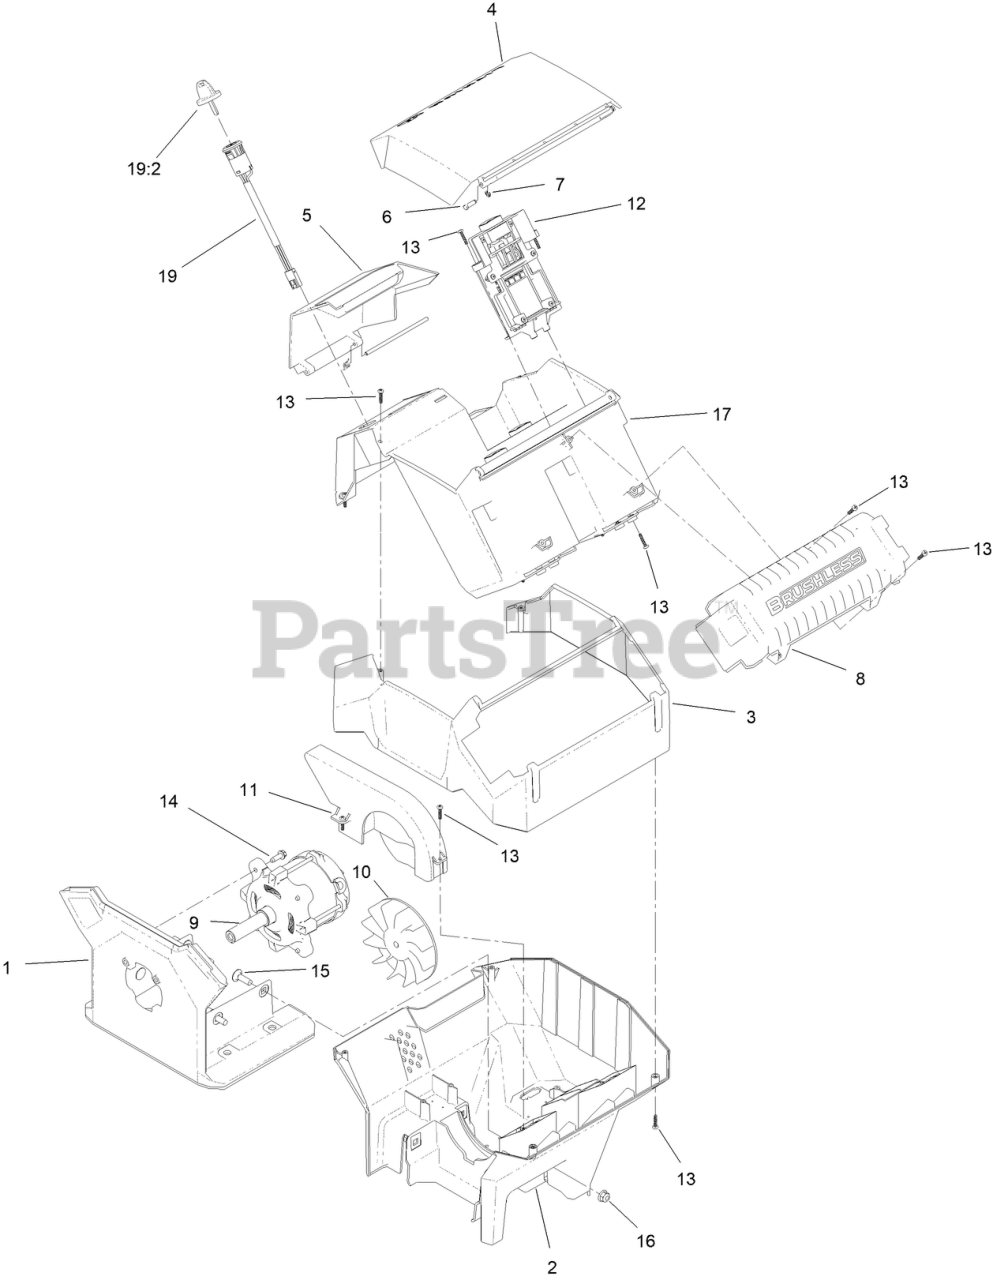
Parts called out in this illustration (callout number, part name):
1	MOTOR MOUNT
2	HOUSING-MOTOR
3	COVER-CONTROLLER
4	DOOR-TOP
5	DOOR-BOTTOM
6	PIN-BATTERY COVER
7	RING-RETAINING
8	MOTOR CONTROLLER ASM-POWERHEAD
9	MOTOR-60V, 2 STAGE
10	FAN-FC
11	COVER-FAN
12	BATTERY TRACK ASSEMBLY
13	SCREW-PPH
14	SCREW-HWHTF
15	BOLT-CARR
16	NUT-HF, NI
17	BUCKET-BATTERY
19	IGNITION ASM-POWERHEAD
19:2	KEY-60V 2 STAGE POWER HEAD
